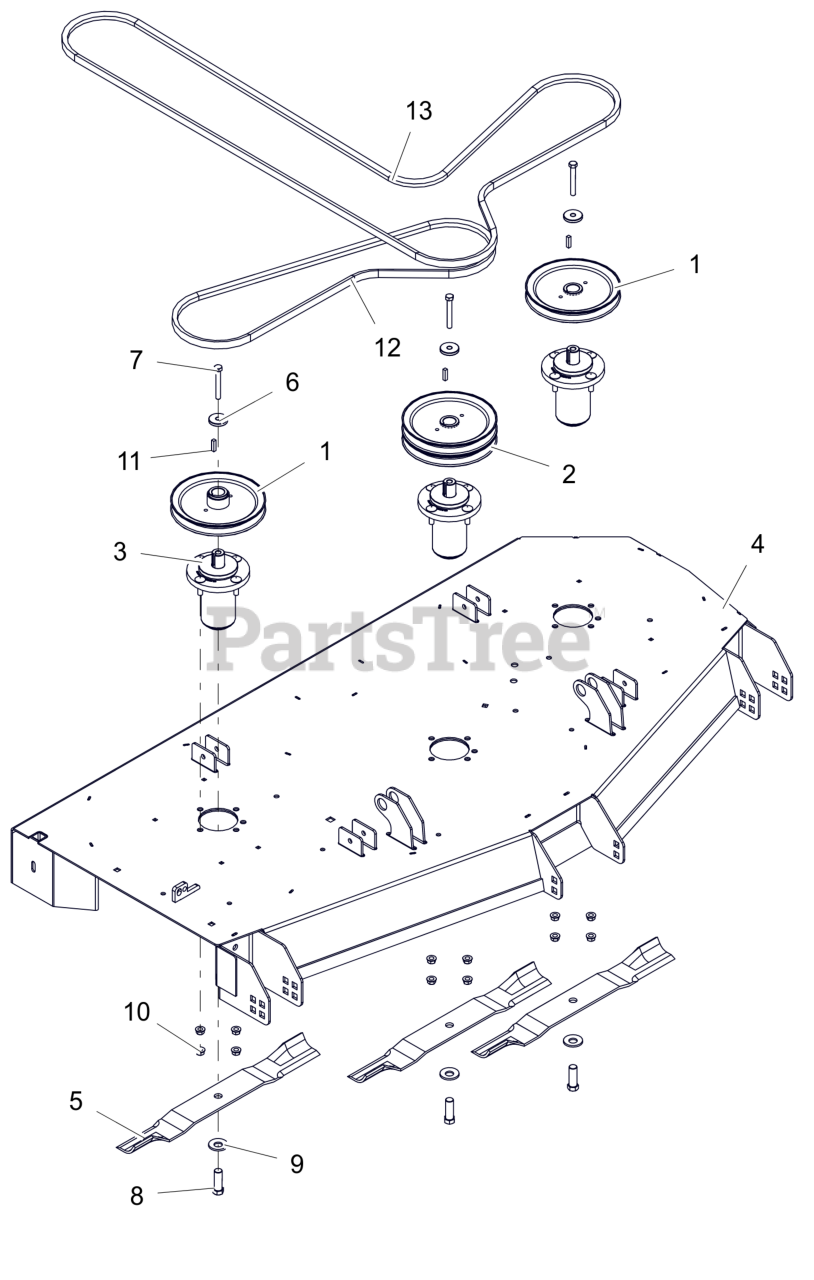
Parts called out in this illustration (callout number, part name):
1	PULLEY, V-7.50 OD X 1"ID
2	PULLEY, DOUBLE 1"X7.50"&7.50" (BLACK)
3	ASM, MAINT FREE ALUM SPINDLE
4	KIT, DECK - 60 W/DECALS - XF3
5	BLADE, 20.5"
6	RETAINER, SHEAVE
7	BLT, HEX .38-16X2.75 G8 ZCC
8	BLT, HEX .62-18X1.75 G8 ZCC
9	WSHR-BLVL .669X1.535X.138
10	NUT-LK-CTR-FLG .375-16 GF ZCC
11	KEY, SQ .25X.25X1.00 RC 40-50
12	V-BELT, B-COGGED
13	V-BELT, HB SECTION
